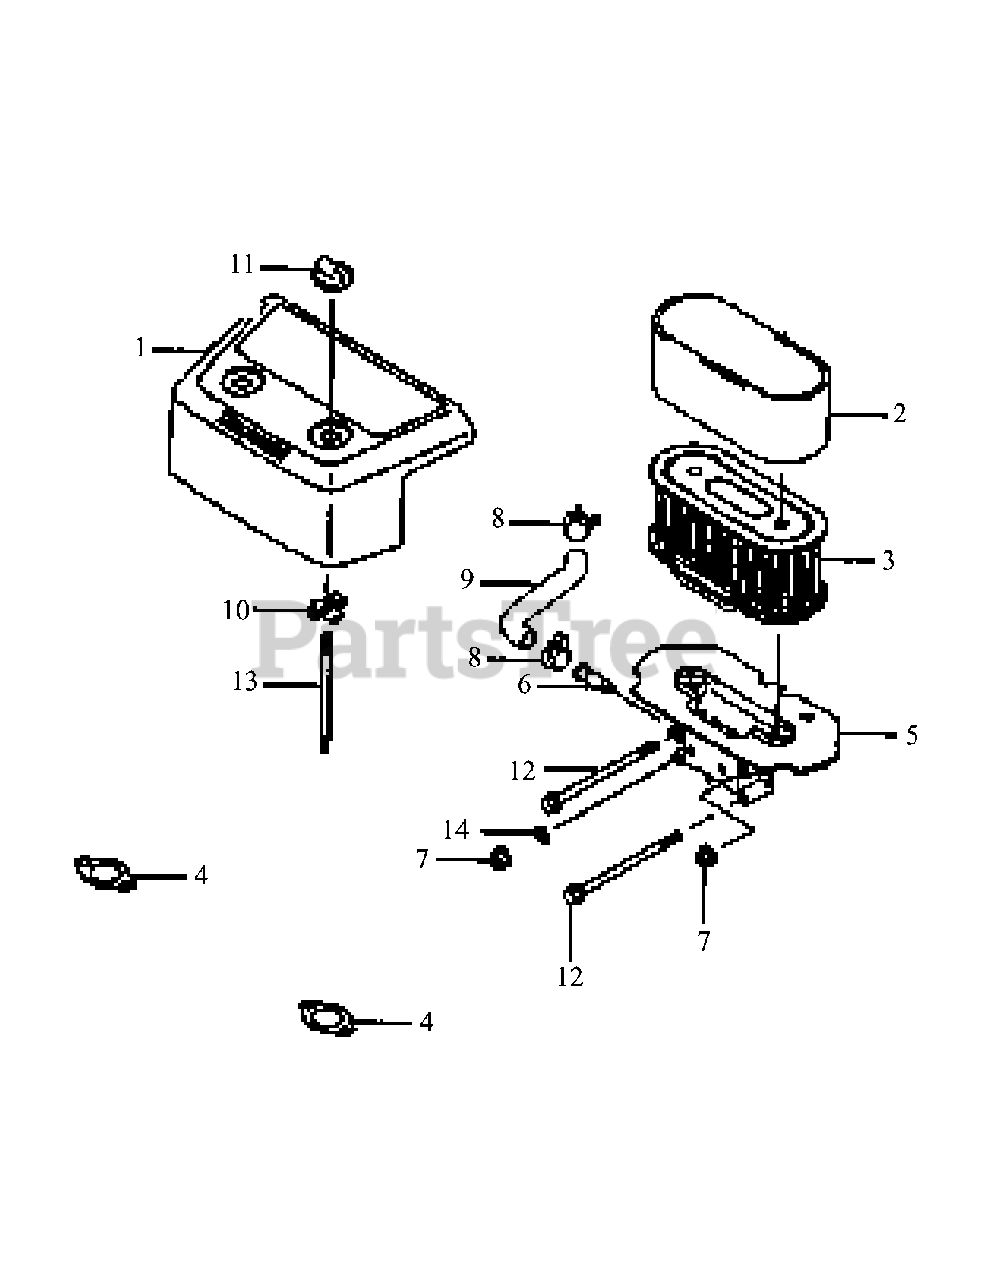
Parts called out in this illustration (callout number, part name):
1	Case-Air Cleaner
2	Element-Precleaner
3	Element-Air Cleaner
4	Gasket-Muffler
8	Clamp
14	Washer-Plain
